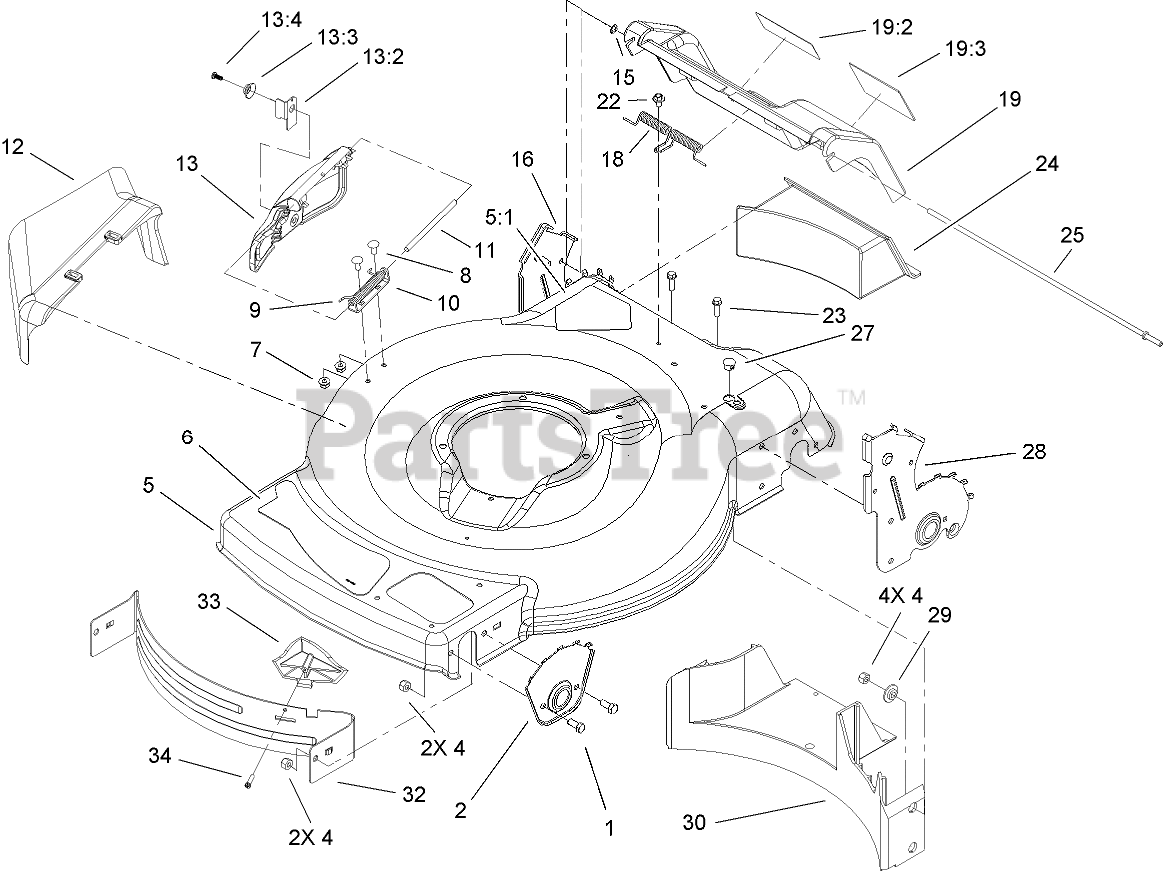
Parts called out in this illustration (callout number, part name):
1	SCREW-HH
2	Plate-HOC, Front
4	NUT-LOCK, NI
5	HOUSING
5:1	DECAL-DANGER
6	Decal-Deck
7	NUT-HHF
8	SCREW-CARR
9	SPRING-TORSION
10	BRACKET-COVER
11	ROD-COVER
12	CHUTE-DISCHARGE, SIDE
13	DISCHARGE DOOR ASM
13:2	LATCH-DOOR
13:3	CAP-DOOR
13:4	SCREW-PLASTITE
15	NUT-PUSH
16	RH REAR HOC PLATE ASM
18	Spring-Door, Rear
19	REAR DOOR ASM
19:2	DECAL-WARNING
19:3	DECAL-WARNING
22	SCREW AND WASHER ASM
23	SCREW-HWH
24	Plug-Discharge, Rear
25	Rod-Pivot, Rear Door
27	Plug-Dome
28	LH REAR HOC PLATE ASM
29	Washer-Stepped
30	Baffle-Rear
32	BAFFLE-FRONT
33	KICKER-FRONT
34	SCREW-PPH
